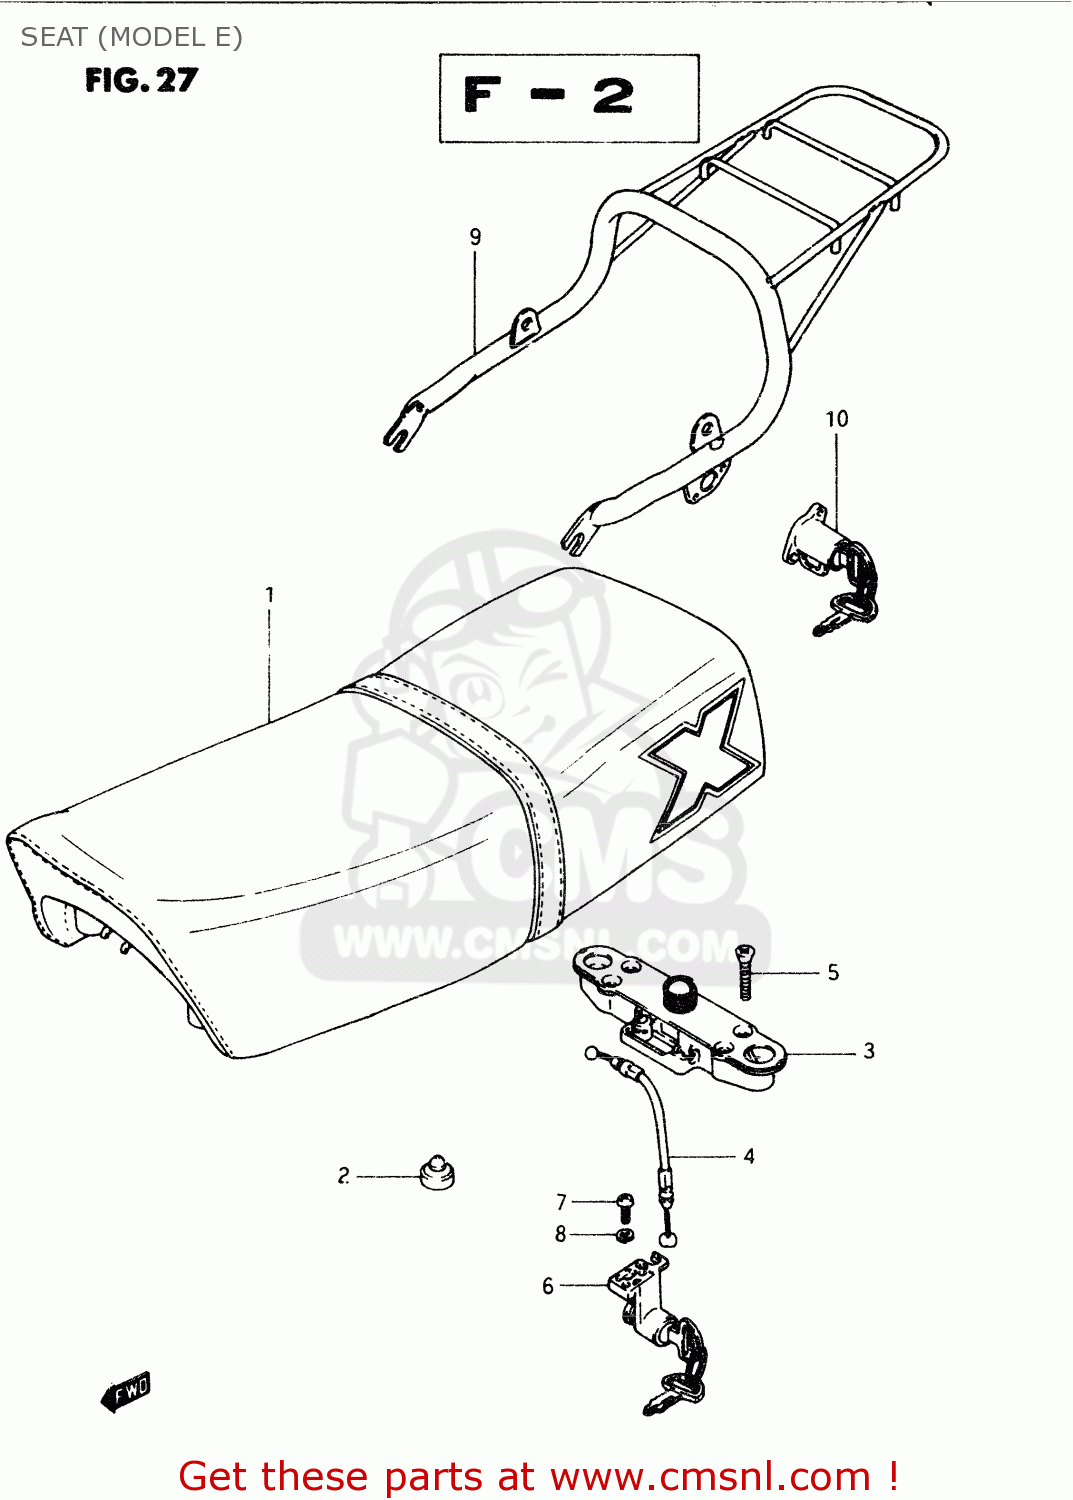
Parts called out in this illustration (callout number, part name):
1	SEAT ASSY (BLUE)
2	CUSHION
3	LOCK ASSEMBLY,SEAT STRIKER
4	CABLE,SEAT LOCK
5	SCREW
6	LOCK SET,SEAT
7	SCREW
8	LOCK WASHER
9	CARRIER
10	LOCK SET,HELMET
